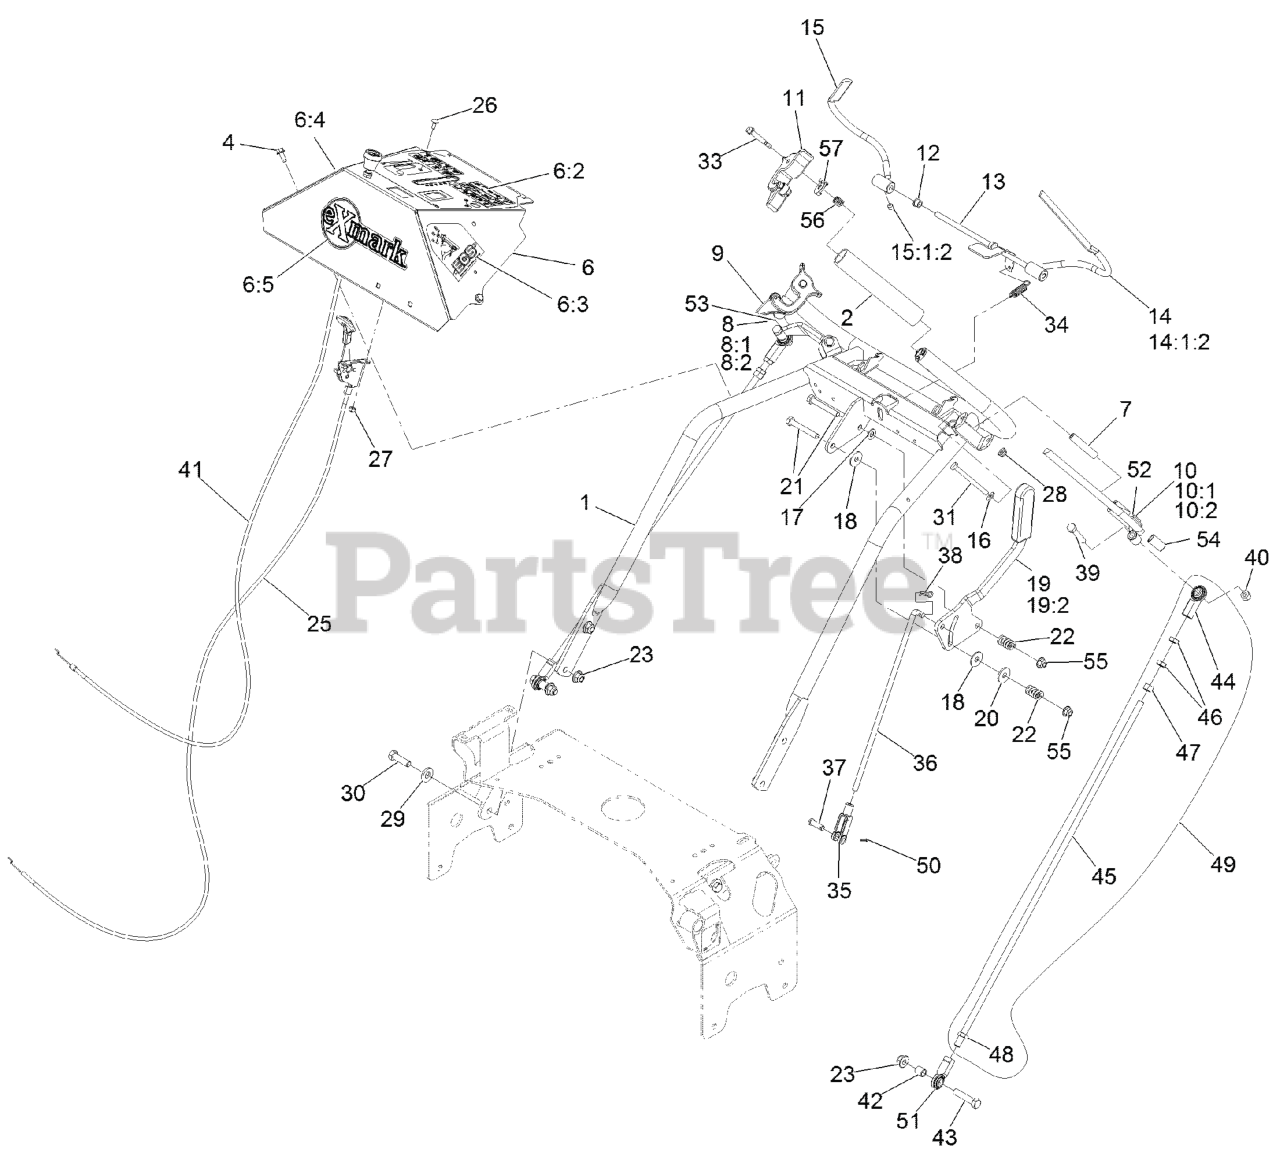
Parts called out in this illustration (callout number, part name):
1	WELD, HANDLE
2	GRIP-BAR, HANDLE
4	SCREW-HWH
6	ASM, CONSOLE W/ DECALS
6:2	DECAL-CONSOLE
6:3	DECAL,LH ECS INSTRUCTION
6:4	DECAL,RH ECS INSTRUCTION
6:5	DECAL, EXMARK LOGO
7	BUSHING-LEVER, DRIVE
8	DRIVE LEVER-ASM, RH
8:1	WLD,RH DRIVE LEVER
8:2	BUSHING, SLEEVE
9	ASM,LATCH RH THUMB
10	DRIVE LEVER-ASM, LH
10:1	WLD,LH DRIVE LEVER
10:2	BUSHING, SLEEVE
11	ASM,LATCH LH THUMB
12	BUSHING-NYLON
13	WLD,OPC LEVER AXLE
14	WLD,LH OPC LEVER
14:1:2	SCREW-SET
15	WLD,RH OPC LEVER
15:1:2	SCREW-SET
16	WASHER-FLAT
17	WASHER-PLAIN
18	WASHER-FRICTION
19	LEVER, SHIFT W/GRIP
19:2	GRIP-HANDLE, STEERING
20	WASHER-FRICTION
21	SCREW-HH
22	SPRING-COMPRESSION
23	NUT-HF, NI
25	CONTROL-THROTTLE
26	BOLT-CARR
27	NUT-LOCK, NI
29	WASHER-BELLEVILLE
30	SCREW-HH
31	SCREW-HH
33	SCREW-SHOULDER
34	SPRING-EXTENSION
35	YOKE-ADJUSTABLE
36	ROD,SPEED CONTROL
37	PIN-CLEVIS
38	PIN-COTTER
39	SCREW-HH
40	NUT-LOCK, NI
41	CABLE, CHOKE
42	SPACER-TUBE, PUMP LINK
43	SCREW-HH
44	JOINT-BALL, END
45	LINK,DRIVE (PLTD)
46	NUT-HJ
47	NUT-HEX
48	NUT-HEX JAM, LH
49	DRIVE LINK ASM
50	PIN-COTTER
51	JOINT-BALL END, LH
52	WLD,LH DRIVE LEVER
53	WLD,RH DRIVE LEVER
54	BUSHING, SLEEVE
55	NUT-HF, NI
56	SPRING-TANK, FUEL
57	LATCH, ECS
